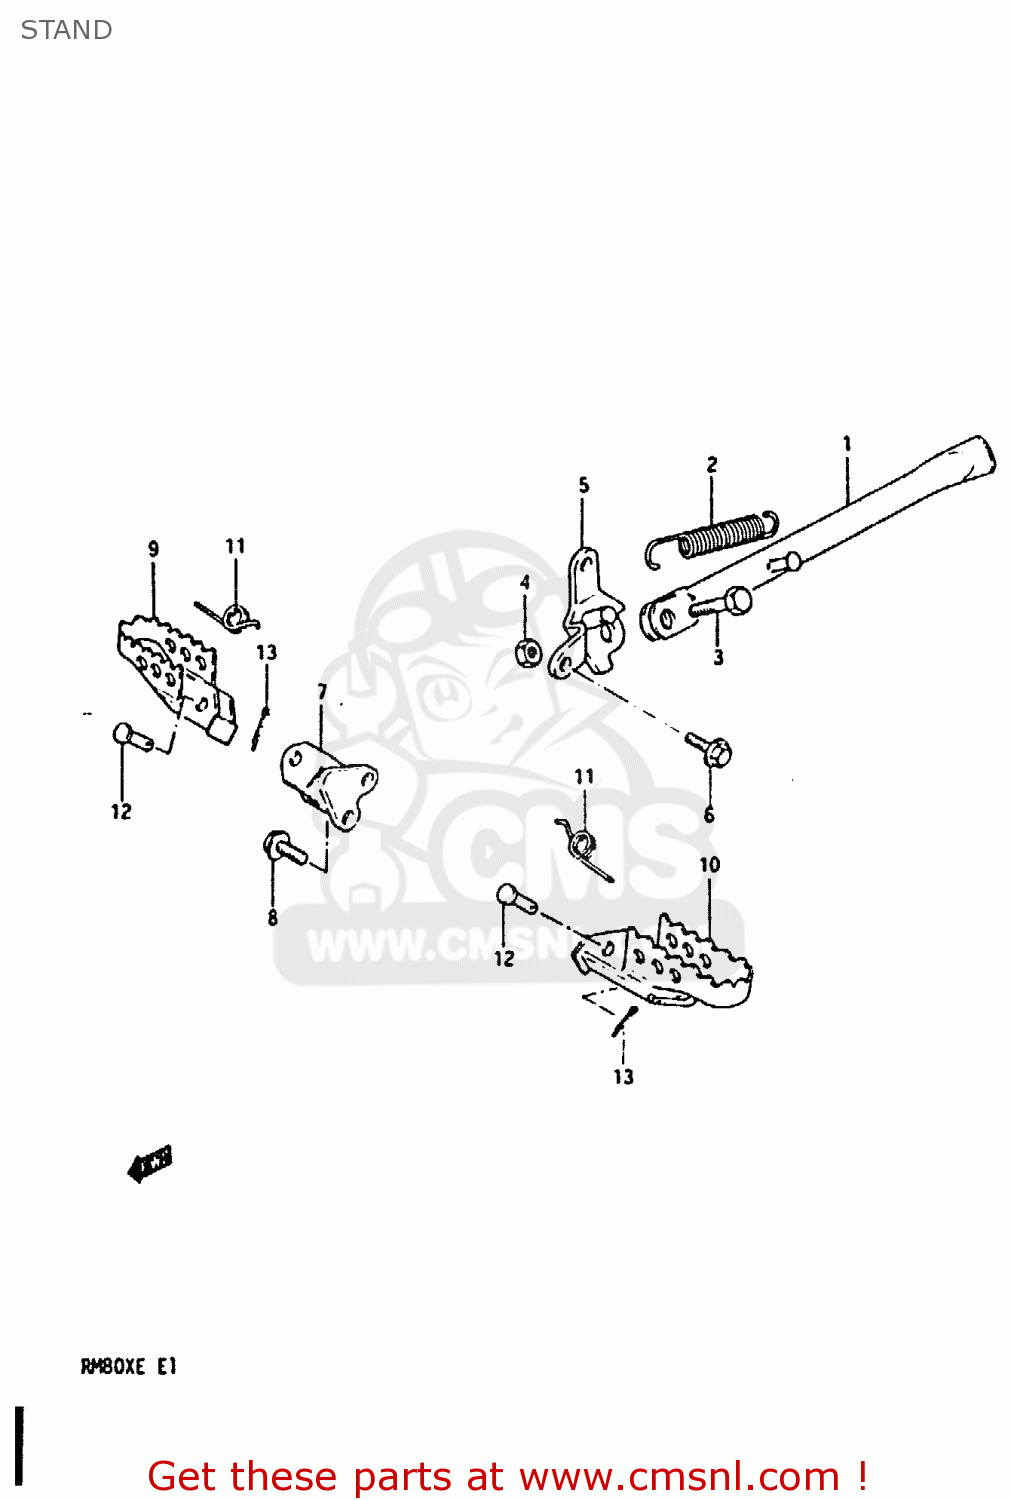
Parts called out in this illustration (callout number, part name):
1	STAND,SIDE
2	SPRING
3	BOLT
4	NUT
5	BRACKET,SIDE STAND
6	BOLT
7	BAR,FRONT FOOTREST
8	BOLT
9	FOOTREST,FRONT,RIGHT
10	FOOTREST,FRONT,LEFT
11	SPRING
12	PIN
13	PIN 20X20
